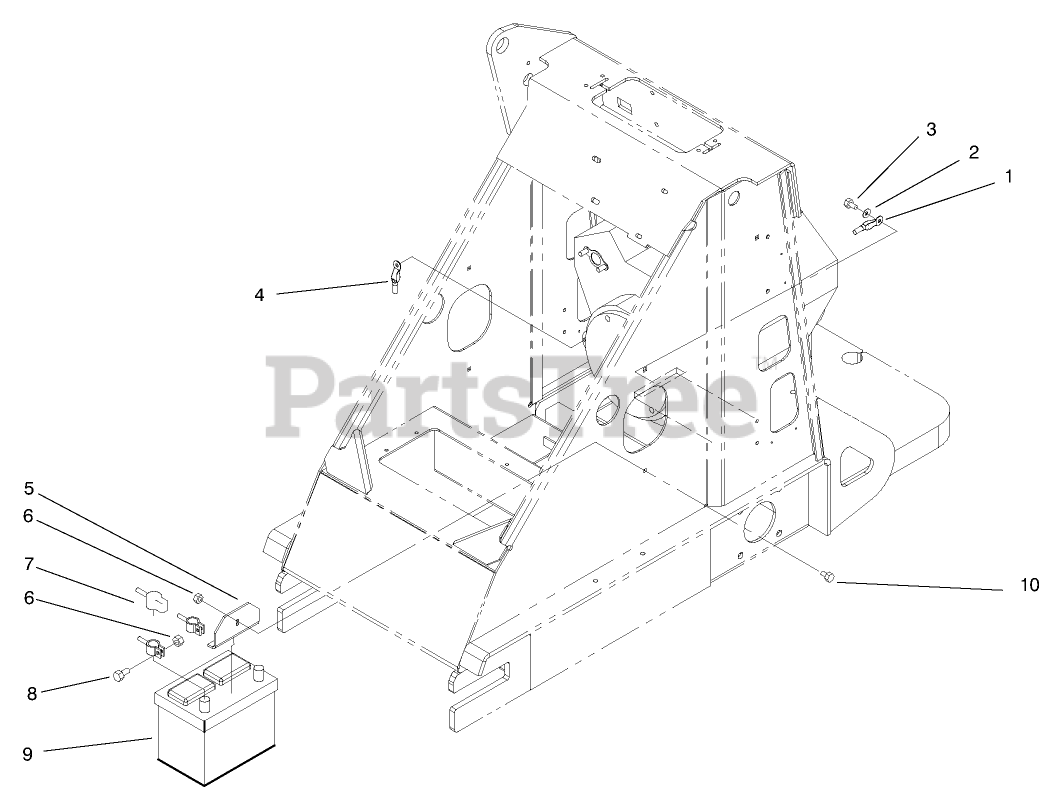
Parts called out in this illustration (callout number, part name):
1	ASSY WIRE
2	WASHER-LOCK
3	SCREW-HH
4	WIRE - BATTERY POSITIVE
5	Clamp-Battery
6	NUT-LOCK, NI
7	BOOT-TERMINAL, RED
8	SCREW-HHF
9	Battery
10	SCREW-CARR
